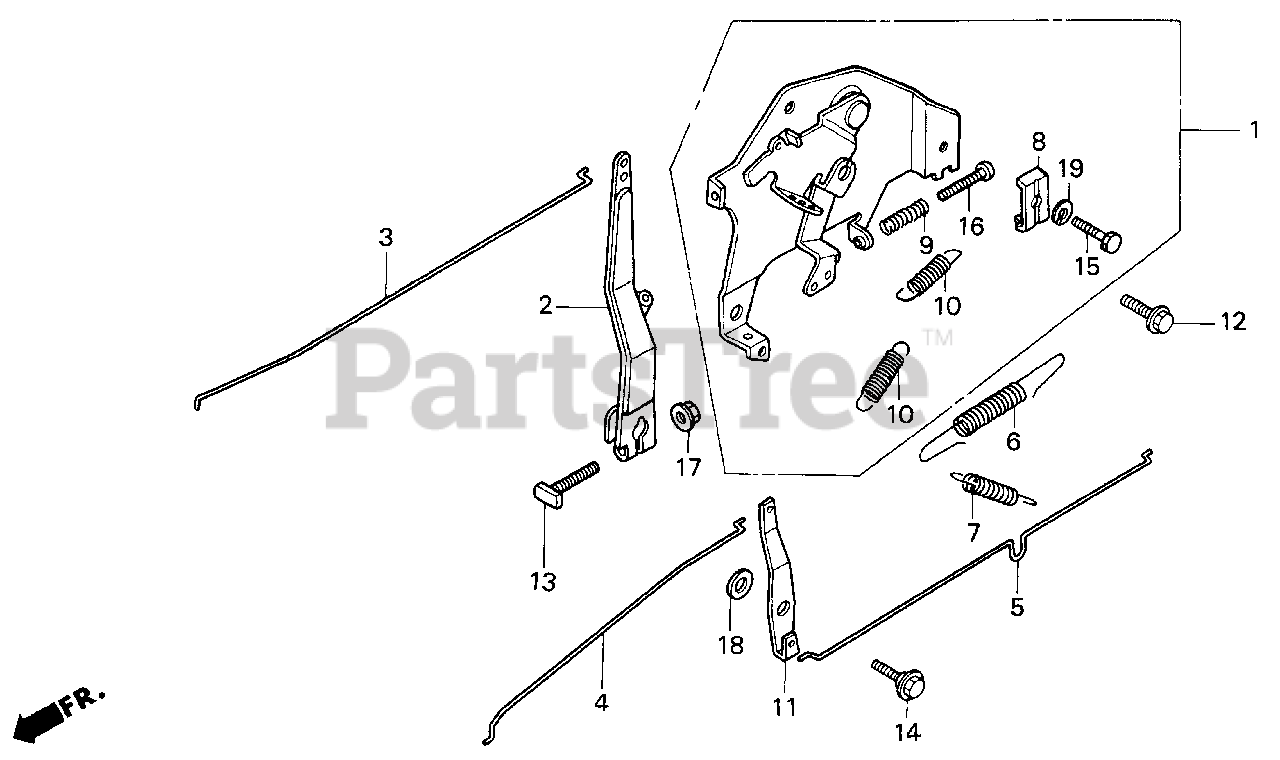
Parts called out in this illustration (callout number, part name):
1	CONTROL ASSY.
2	ARM, GOVERNOR
3	ROD, GOVERNOR
4	ROD, CHOKE
5	ROD, JOINT
6	SPRING, GOVERNOR
7	SPRING, GOVERNOR PRIMARY
8	HOLDER, CABLE
9	SPRING, CONTROL ADJUSTING
10	SPRING, CABLE RETURN
11	LEVER, CHOKE JOINT
12	BOLT, FLANGE (6X12) (CT200)
13	BOLT, GOVERNOR ARM
14	BOLT, FLANGE (6MM)
15	BOLT, RECESSED (5X16)
16	SCREW, PAN (5X20)
17	NUT, FLANGE (6MM)
18	WASHER, PLAIN (6MM)
19	WASHER, SPRING (5MM)
